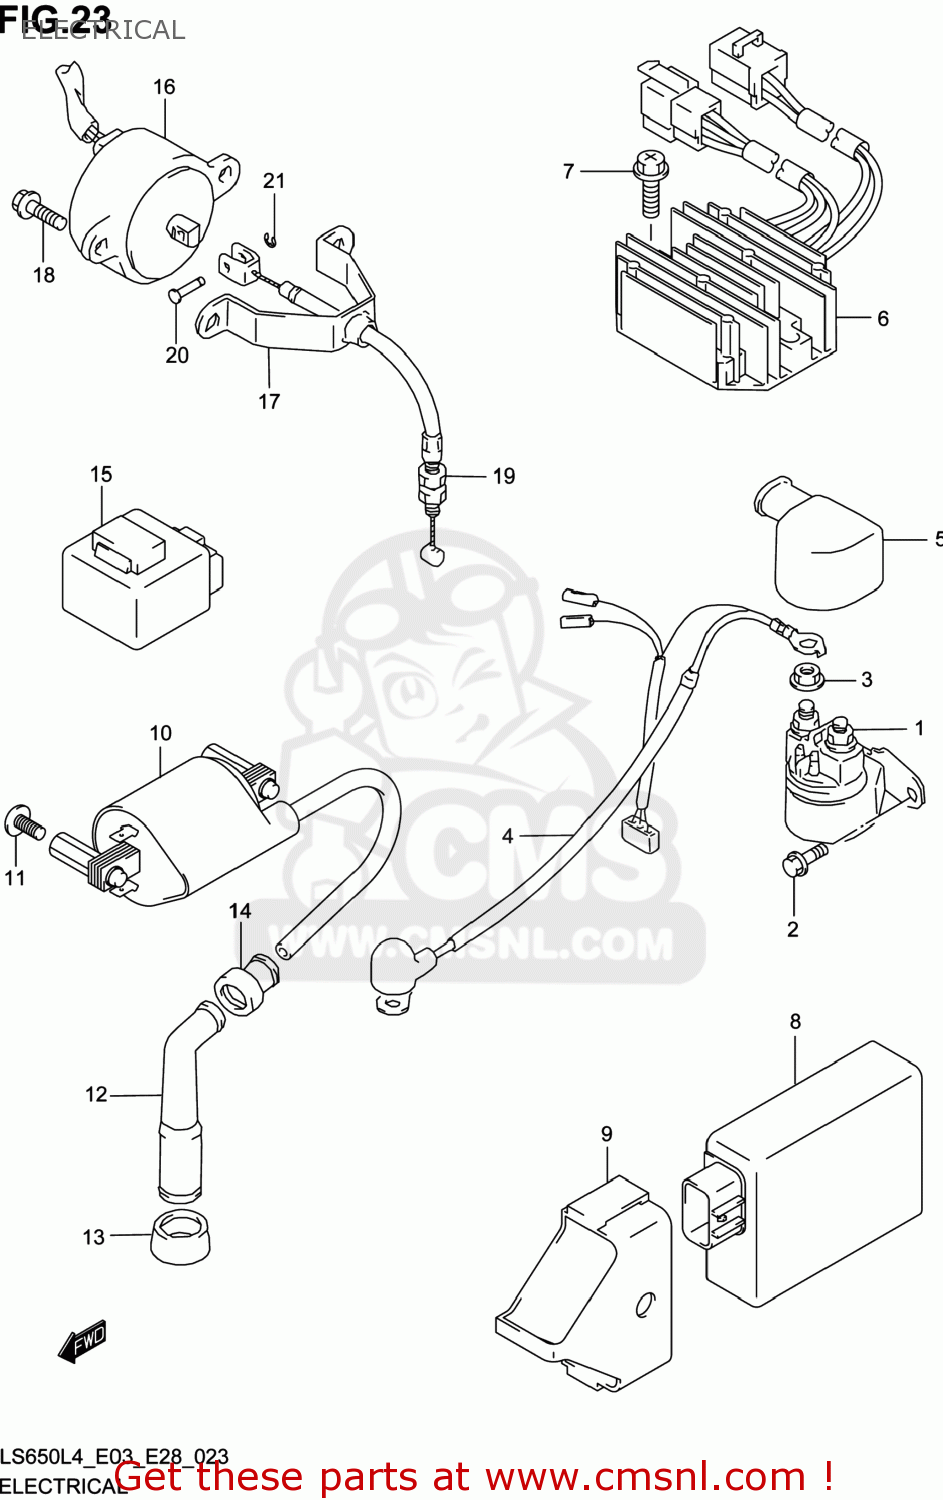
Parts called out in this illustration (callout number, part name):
1	RELAY ASSY,STARTING MOTOR
2	BOLT
3	NUT
4	WIRE,STARTER MOTOR
5	CAP,STARTER RELAY TERMINAL
6	RECTIFIER ASSY
7	SCREW
8	IGNITOR ASSY
9	CUSHION,IGNITOR
10	COIL ASSY,IGNITION
11	SCREW
12	CAP ASSY,SPARK PLUG
13	SEAL,SPARK PLUG
14	SEAL,HIGH TENSION CORD
15	CONTROL UNIT,DECOMP
16	SOLENOID ASSY,DECOMP
17	BRACKET,DECOMP SOLENOID
18	BOLT
19	CABLE ASSY,DECOMP
20	PIN(4X12.5)
21	E RING
